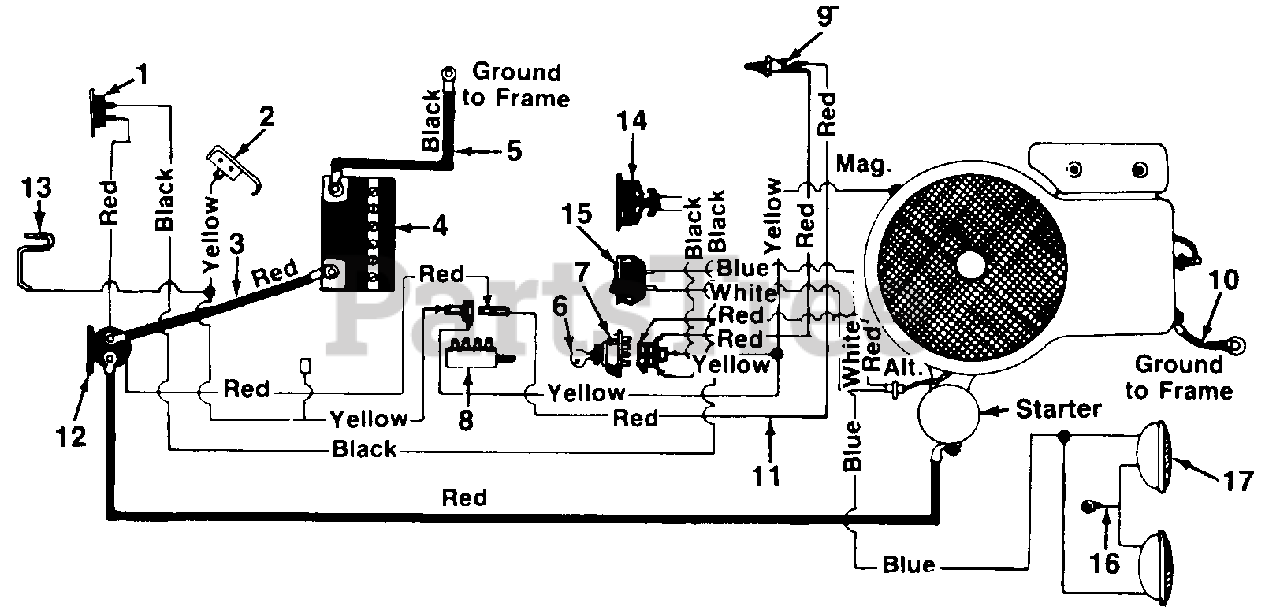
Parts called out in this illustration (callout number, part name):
1	Circuit Breaker
2	Reverse Safety Switch
3	Electric Wire w/Boot
4	1 2V-Battery
5	Ground Wire 9.0" Lg.
6	Ignition Key
7	Ignition Switch
8	Safety Switch
9	Safety Switch
10	Ground Wire 7.25" Lg.
11	Wire Harness
12	Solenoid
13	Spring Switch
14	Ammeter
15	Light Switch
16	Ground Wire
17	Headlight
